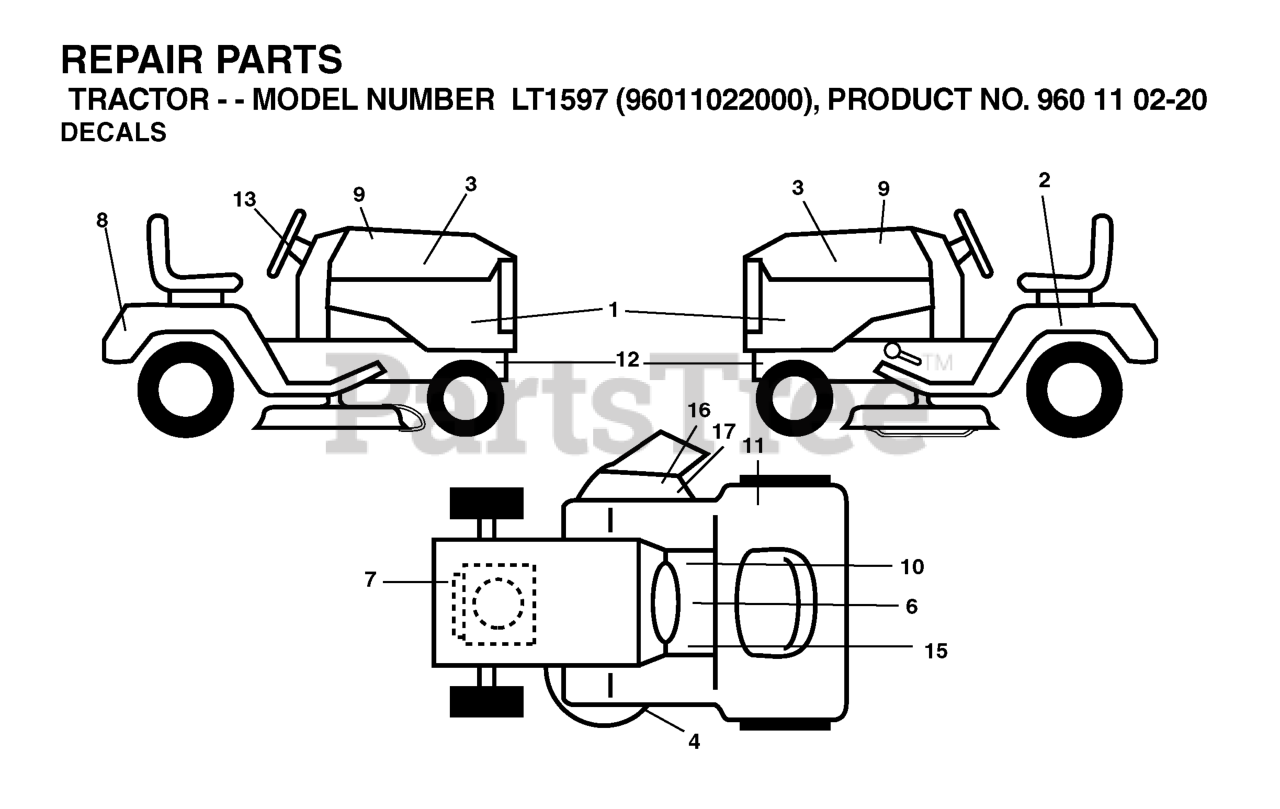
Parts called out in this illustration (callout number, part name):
2	DECAL BTRY SYMBOLS
3	DECAL.HOOD.HUSQVARNA.INTERNATI
4	DECAL.V-BELT.SCHEMATIC.36/38/9
6	LABEL
7	DECAL
10	DECAL PARK BRAKE
11	DECAL
13	DECAL.STEERING.HUSQ.BLUE
15	DECAL
16	DECAL.INTERNATIONL.CUTFINGER
17	DECAL, DEFLECT WARNING
